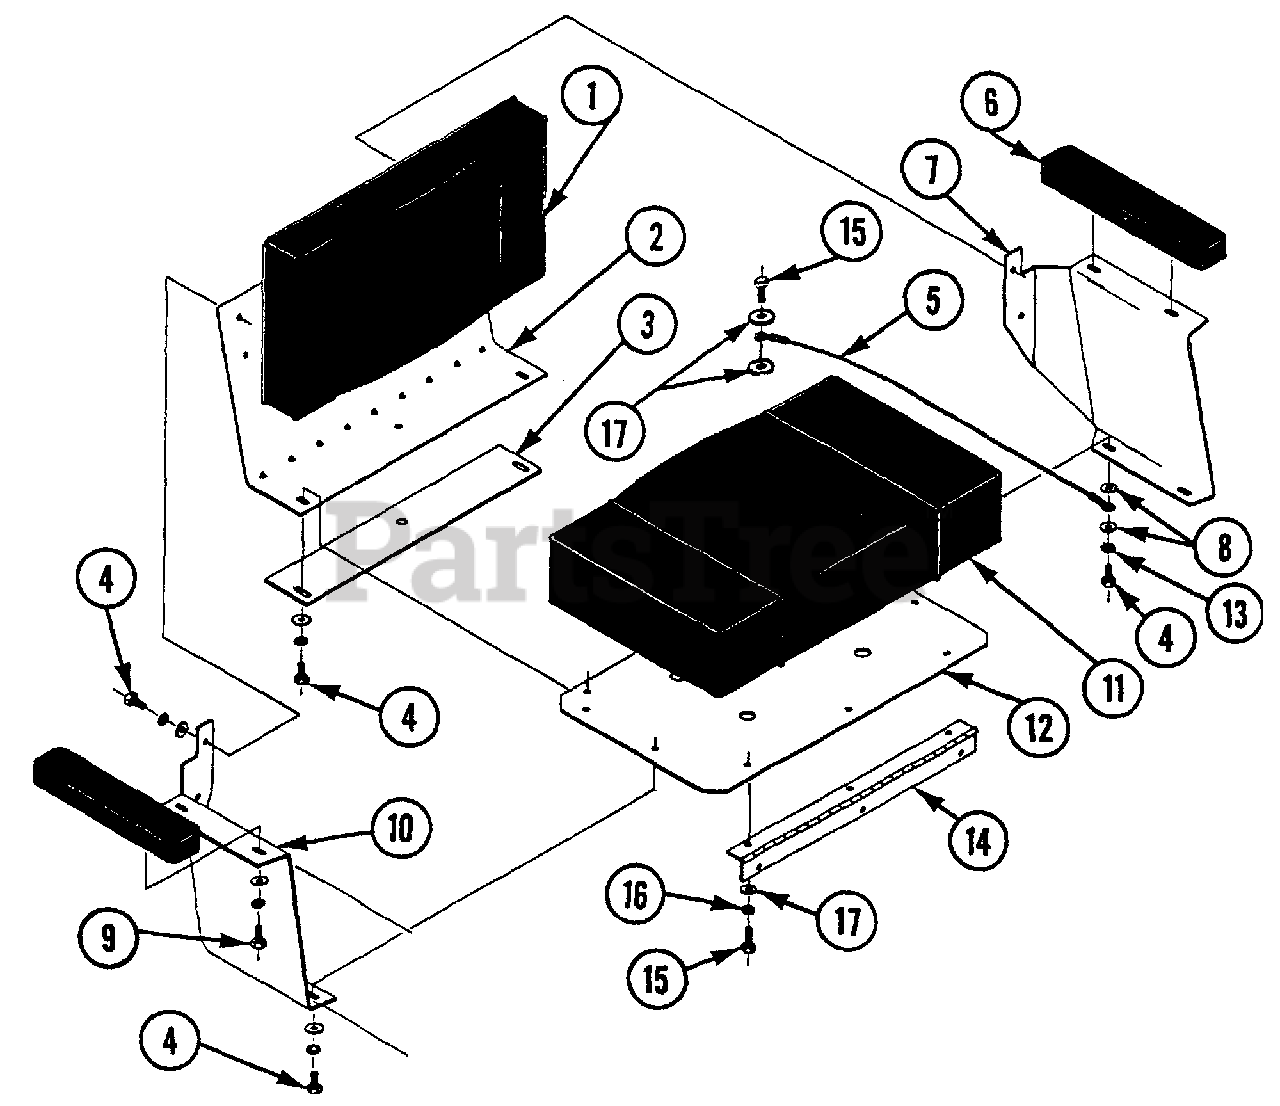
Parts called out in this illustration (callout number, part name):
1	BACK CUSHION ASSEMBLY
2	BACK REST SUPPORT
3	ACTUATOR WELDMENT, SEAT SWITCH
4	CAPSCREW, HEX, 5/16-18 X 1, GRADE 5
5	CABLE ASSEMBLY, SEAT
6	ARM CUSHION ASSEMBLY
7	ARM SUPPORT LEFT
8	WASHER, 5/16 STD, FLAT
9	CAPSCREW, HEX, 5/16-18 X 3/4, GRADE 5
10	ARM SUPPORT RIGHT
11	SEAT CUSHION ASSEMBLY
12	BOTTOM, SEAT SUPPORT
13	LOCKWASHER, 5/16 HEAVY, SPLIT SPRING
14	SEAT HINGE
15	CAPSCREW, HEX, 5/16-18 X 1, GRADE 5
16	LOCKWASHER, 5/16 STD, SPLIT SPRING
17	WASHER, 5/16 STD, FLAT
